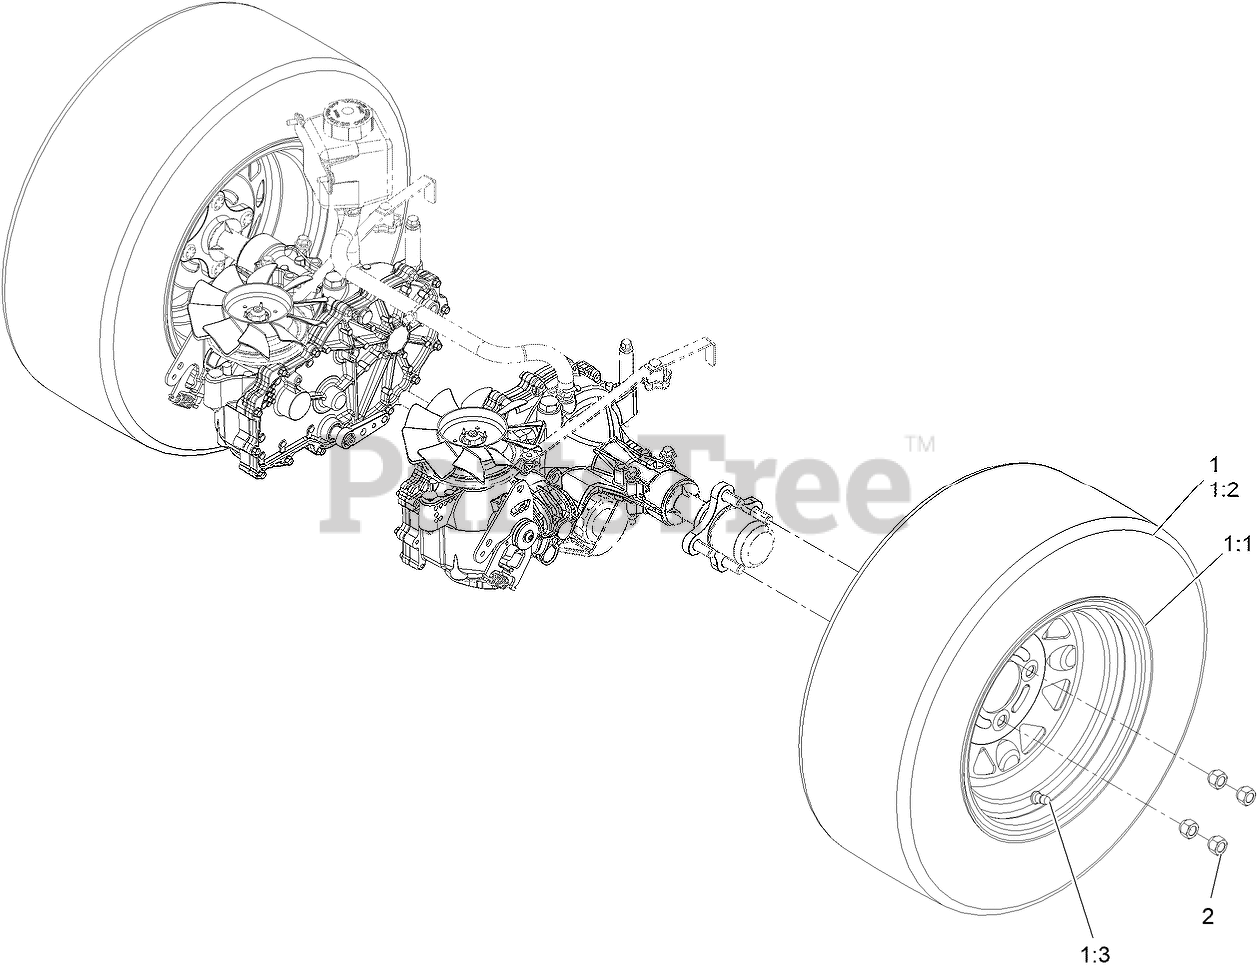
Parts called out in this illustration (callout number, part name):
1	WHEEL AND TIRE ASM
1:3	VALVE
2	NUT-LUG
